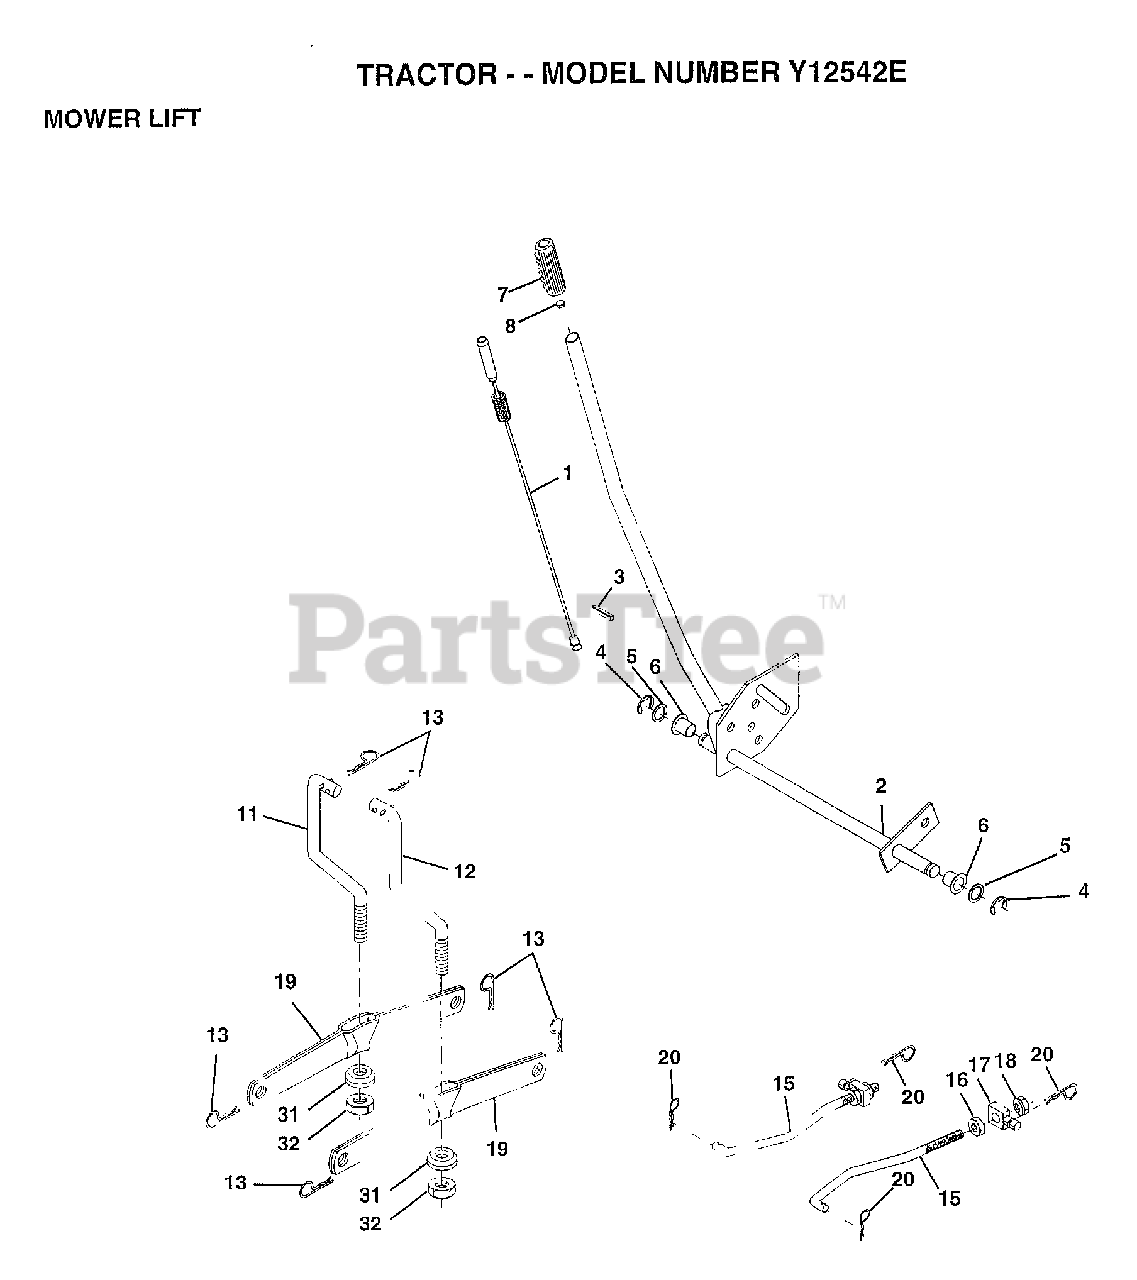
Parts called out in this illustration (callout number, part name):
1	WIRE ASM W.SPRING
2	SHAFT ASM LFT LH
3	PIN GROOVE
5	WASHER
6	NYLON BEARING
7	GRIP
15	LINK.FRONT
16	NUT
17	TRUNION
18	NUT.LK.W/WSH.1/2.
19	ARM SUSP REAR
20	RETAINER.SPRING
31	BEARING PVT LH
32	NUT.CROWNLOCK.3/8
